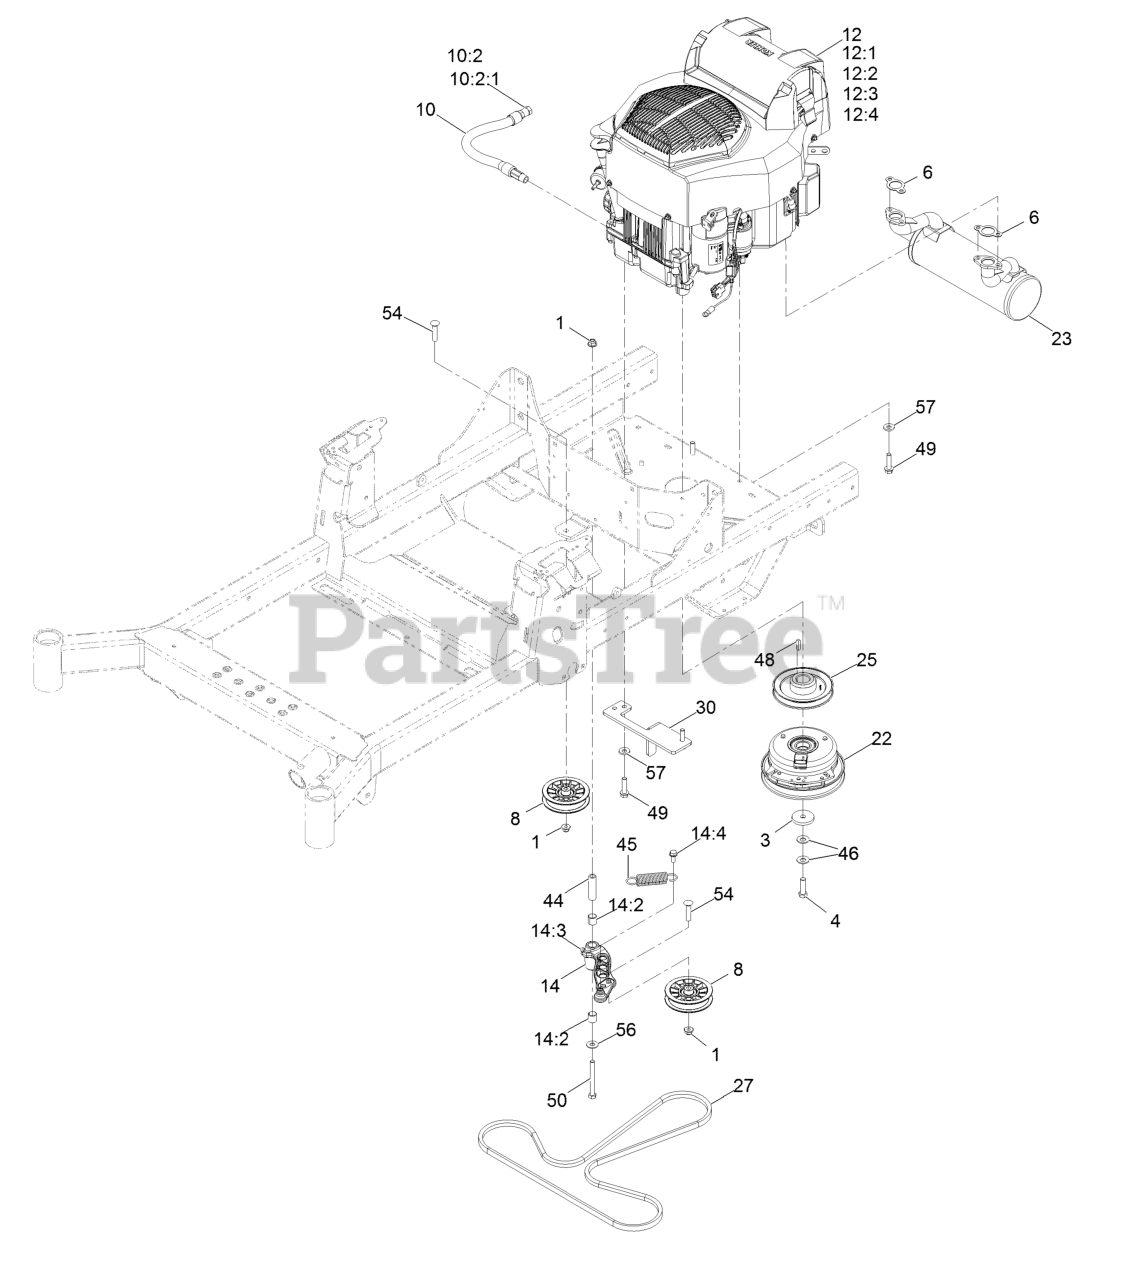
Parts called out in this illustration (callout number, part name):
1	Nut-Nyloc 3/8-16 Flg
3	Washer-Clutch
4	Screw-HH 7/16-20 X 1 1/2 W/Loctite
6	Gasket-Exhaust
8	Pulley-Flat
10	Oil Drain Hose ASM
10:2	Plug-W/O-Ring
10:2:1	O-Ring
12:1	Kohler 16 083 01-S Engine Air Filter
12:2	Kohler 25 050 44-S Engine Oil Filter
12:3	Kohler 24 050 13-S Fuel Filter
12:4	Kohler 25 083 04-S Safety Filter
14	Idler Arm ASM
14:2	Sleeve-Bearing
14:3	Zerk-90deg 1/4-28
14:4	Screw-HWH 5/16-18 X 3/4 Tf
23	Muffler-Kohler Aes
25	Sheave (W/Hub)
27	Belt-V
30	Anchor-Clutch
44	Bushing-Pivot, Idler
45	Spring-Extension
46	Washer-Spring Disc 7/16
48	Key-Machine 1/4 X 1/4 X 1
49	Screw-HWH 3/8-16 X 1 1/2 Taptite
50	Screw-HH 3/8-16 X 3 1/2
54	Bolt-Carriage 3/8-16 X 1 3/4
56	Washer-3/8 Std
57	Washer-Spring Disc 3/8
